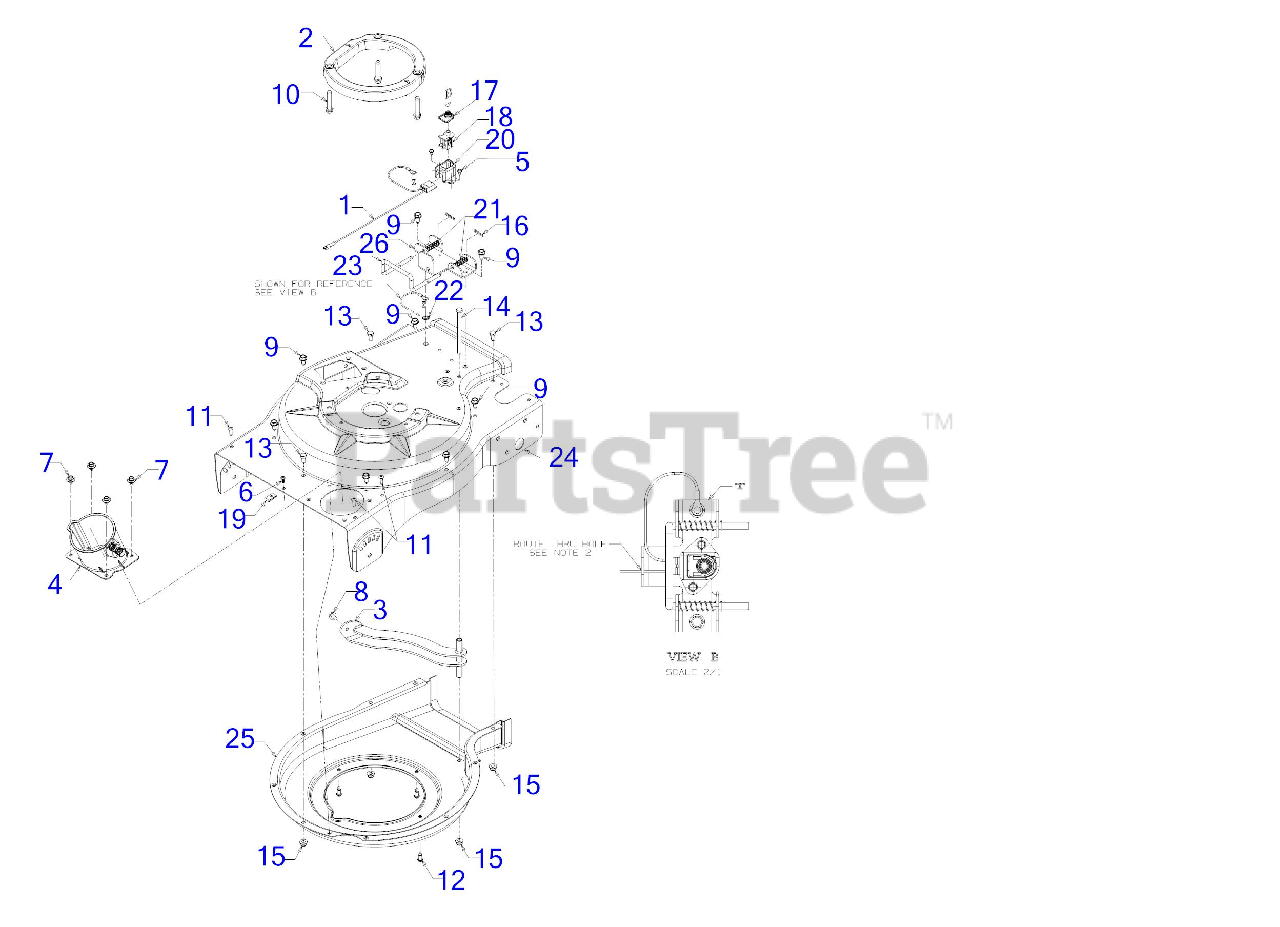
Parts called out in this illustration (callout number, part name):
1	WIRE HARNESS ASSEMBLY
2	ENGINE SPACER ASSEMBLY
3	SCREEN ASSEMBLY
4	HOSE ADAPTER BASE ASSEMBLY
5	HEX SCREW AB-TAP #10-16 x 0.500
6	SCREW #10-16 x 0.500
7	SCREW 1/4-20 x .50
8	SCREW 5/16-18 x .500
9	SCREW 5/16-12 x .750
10	SCREW 3/8-16 x 1.875
11	SCREW #12-16 x .750
12	SCREW .30 x .46
13	SCREW 5/16-18X .625 GR5
14	SCREW 5/16-18 x 4.5 GR5
15	FLANGE LOCK NUT 5/16-18
16	COTTER PIN .072 DIA
17	SWITCH COVER
18	SNAP MOUNT SWITCH
19	U-TYPE SPEED NUT
20	SWITCH COVER
21	COMPRESSION SPRING
26	MOUNTING BRACKET
